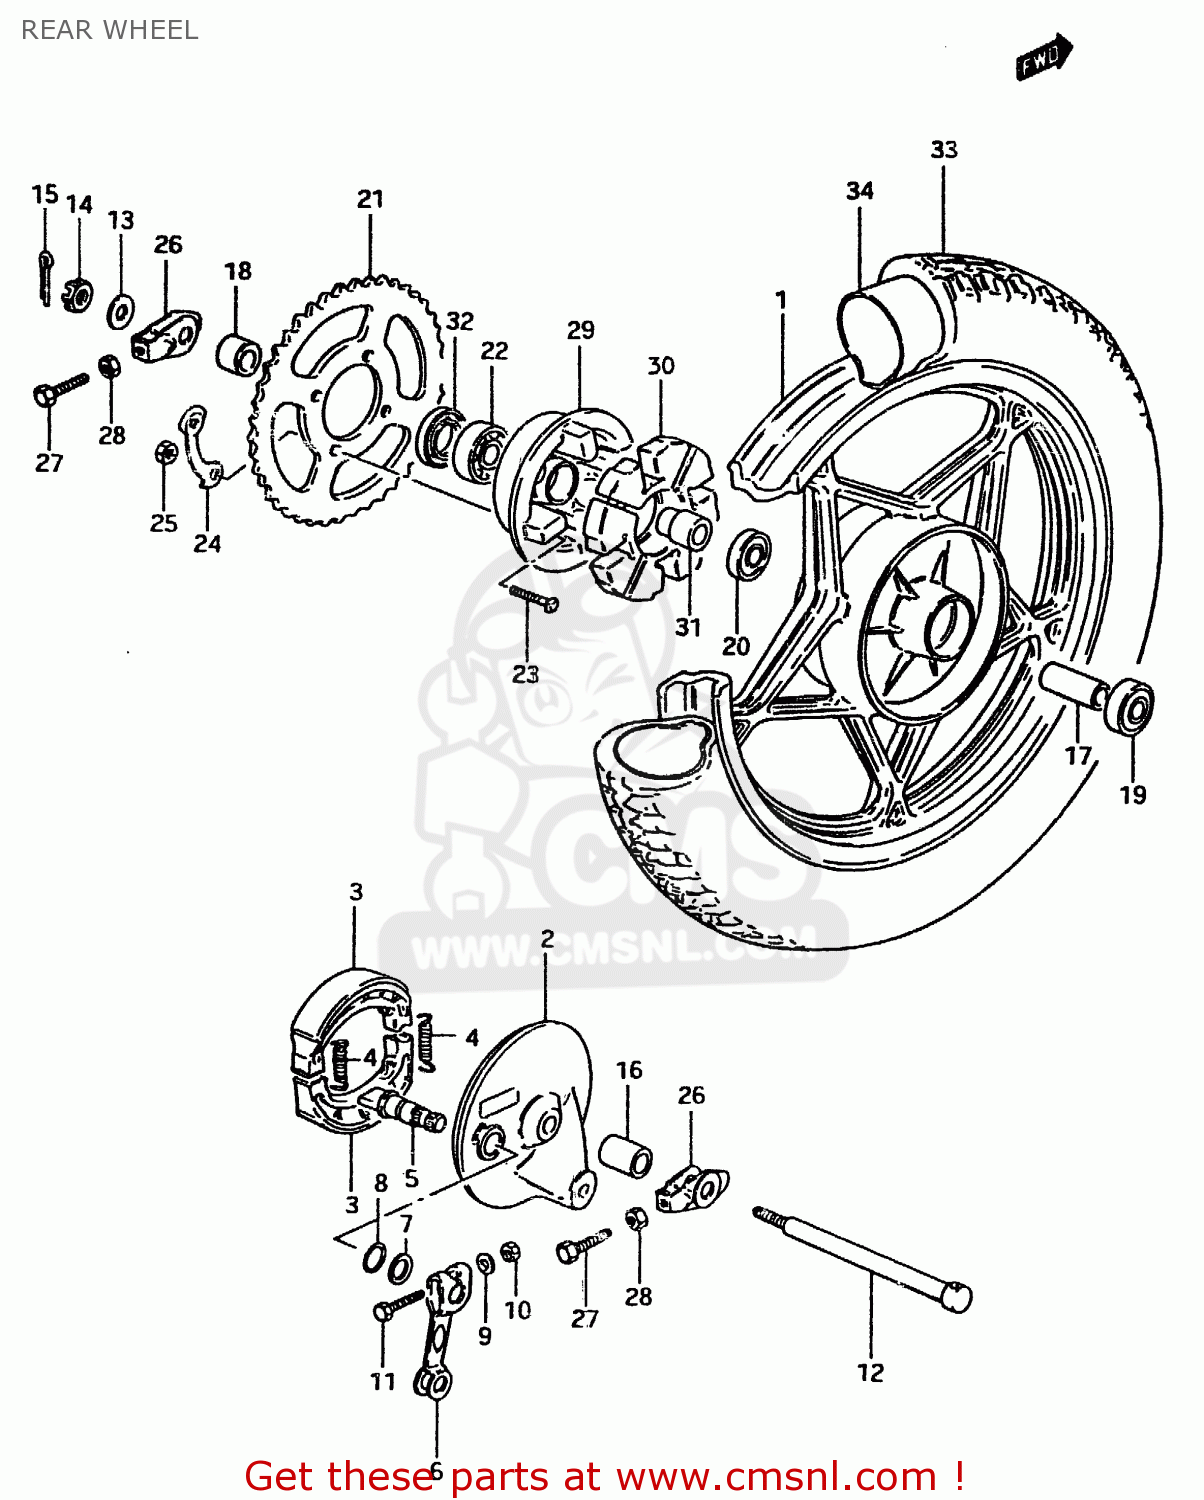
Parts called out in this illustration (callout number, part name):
1	WHEEL, REAR (160X18)
2	PANEL, REAR HUB
3	SHOE,BRAKE (MCA)
4	SPRING(L:34)
5	CAM,FRONT BRAKE
6	LEVER, BRAKE CAM
7	WASHER (14.5X22X1.6)
8	O-RING (D:2.4 ID:13.8)
9	WASHER
10	NUT
11	BOLT(6X33)
12	AXLE,FRONT
13	WASHER
14	NUT 12MM
15	COTTER PIN
16	SPACER, AXLE RH
17	SPACER (12.6X19X58)
18	SPACER 12X25X2
19	BEARING
20	BEARING
21	SPROCKET,RR NT
22	BEARING
23	BOLT(8X33.5)
24	WASHER
25	NUT
26	27
27	BOLT(6X38)
28	NUT
29	DRUM,REAR SPROCKET MOUNT
30	ABSORBER,RR HUB SHOCK
31	RETAINER,RR SPROCKET DRUM
32	SEAL OIL(25X40X6)
33	TIRE 2.75-18 070-458MM
34	TUBE,INNER
